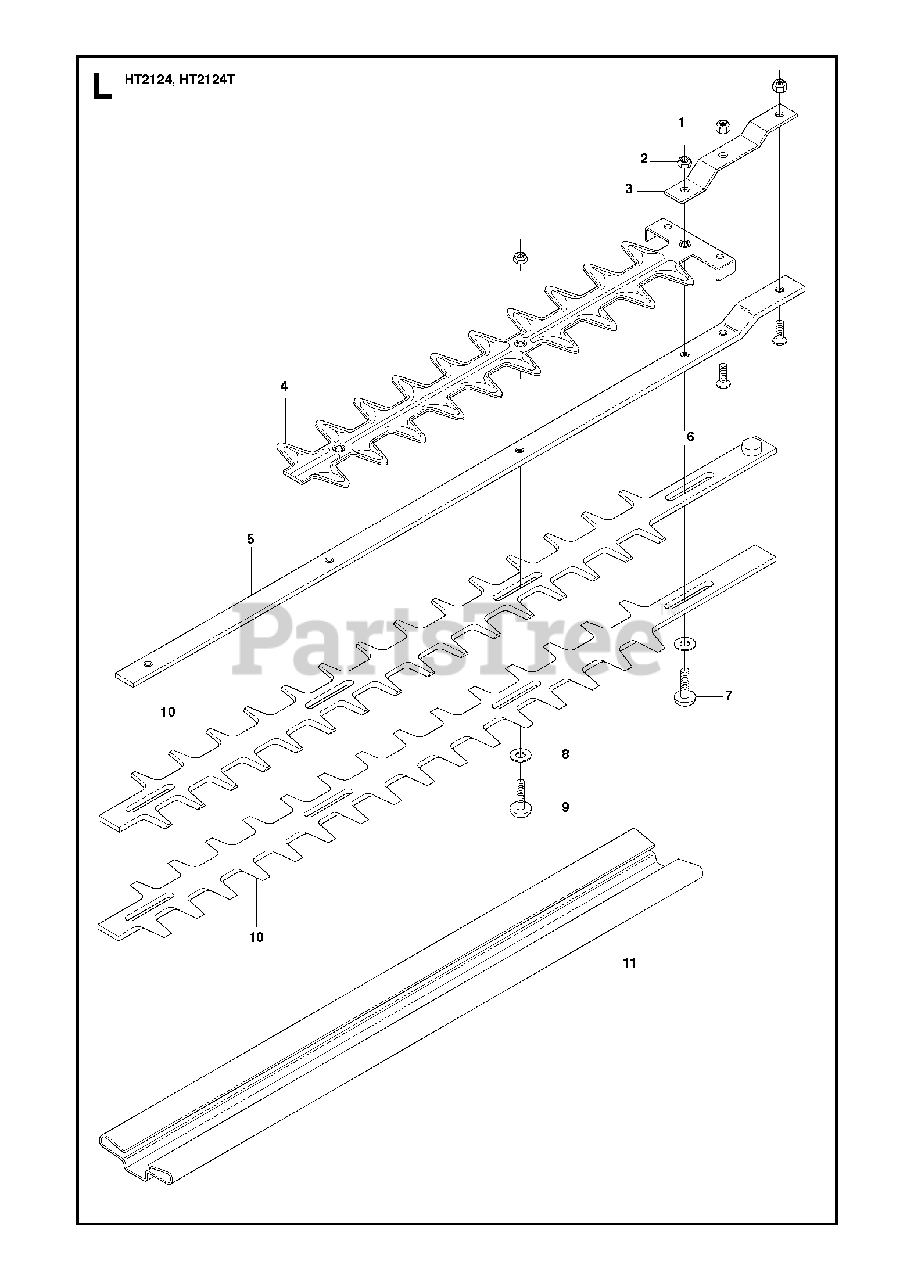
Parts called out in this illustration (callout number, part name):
5	PLATE
5	GUIDE PLATE
10	BLADE
11	PROTECTOR
11	COVER
